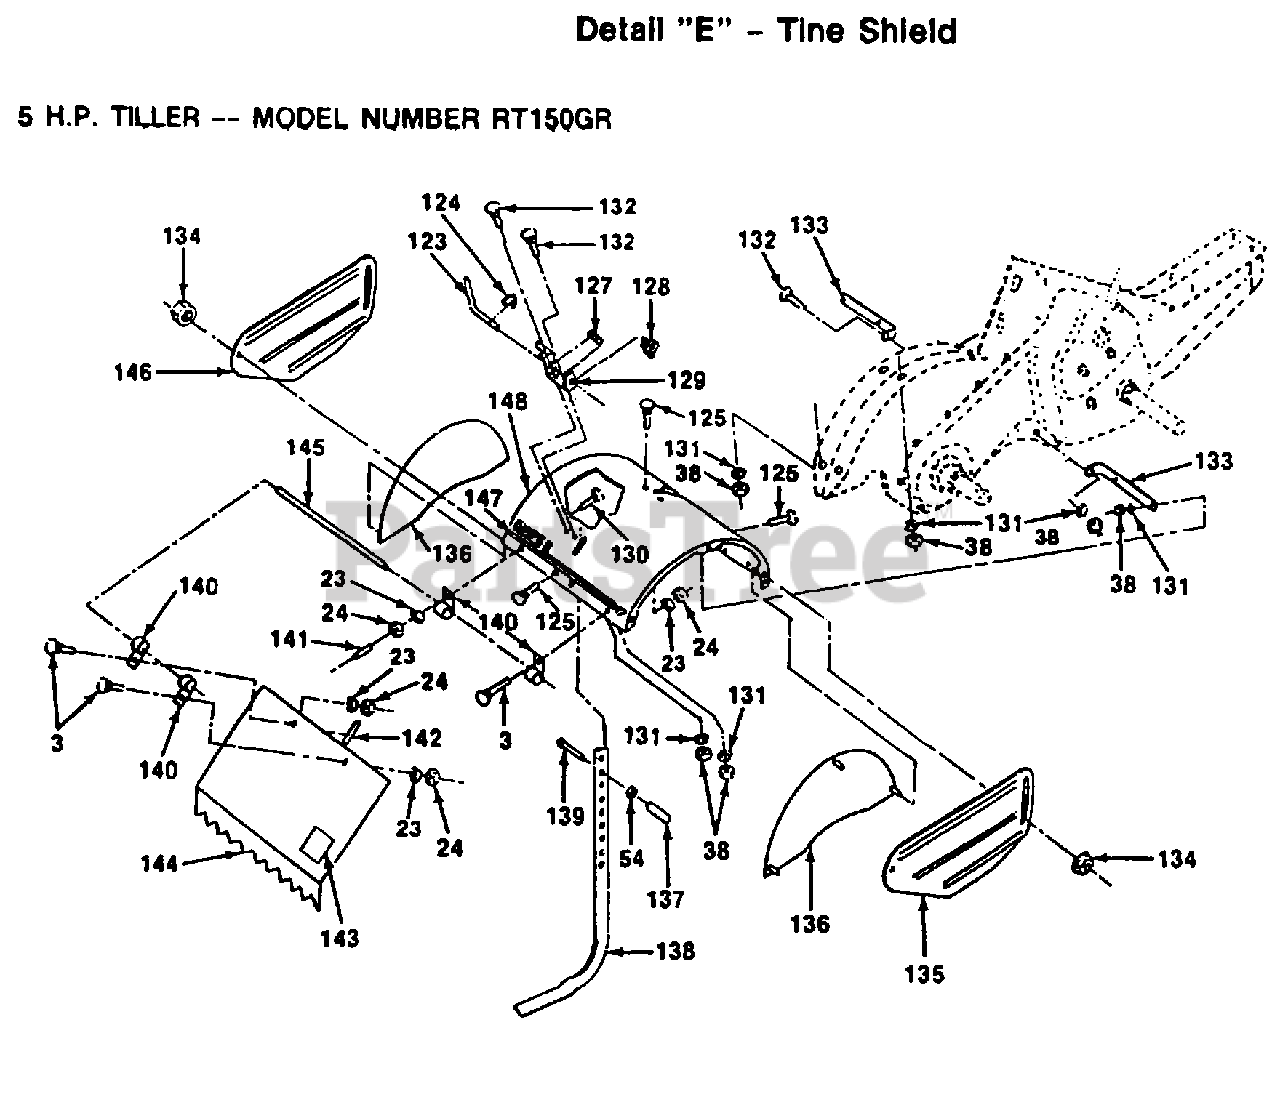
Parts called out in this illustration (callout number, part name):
3	BOLT
23	LOCKWASHER
38	NUT.HEX.5/16-18
54	NUT.HEX.3/8-16UNC
123	STAKE PIN TI
124	KLIP RING TI
125	BOLT
127	SPRING TI
128	SPRING CRT
129	LATCH BRACKET TI
130	BOLT
131	LOCKWASHER
132	BOLT CRT
134	NUT
136	SHIELD CRT
137	GRIP CRT
139	BOLT
140	HINGE CRT
141	VINYL CAP TI
142	PAD IDLER TI
145	PIN HINGE
146	SHIELD.SD.OUT.LH
